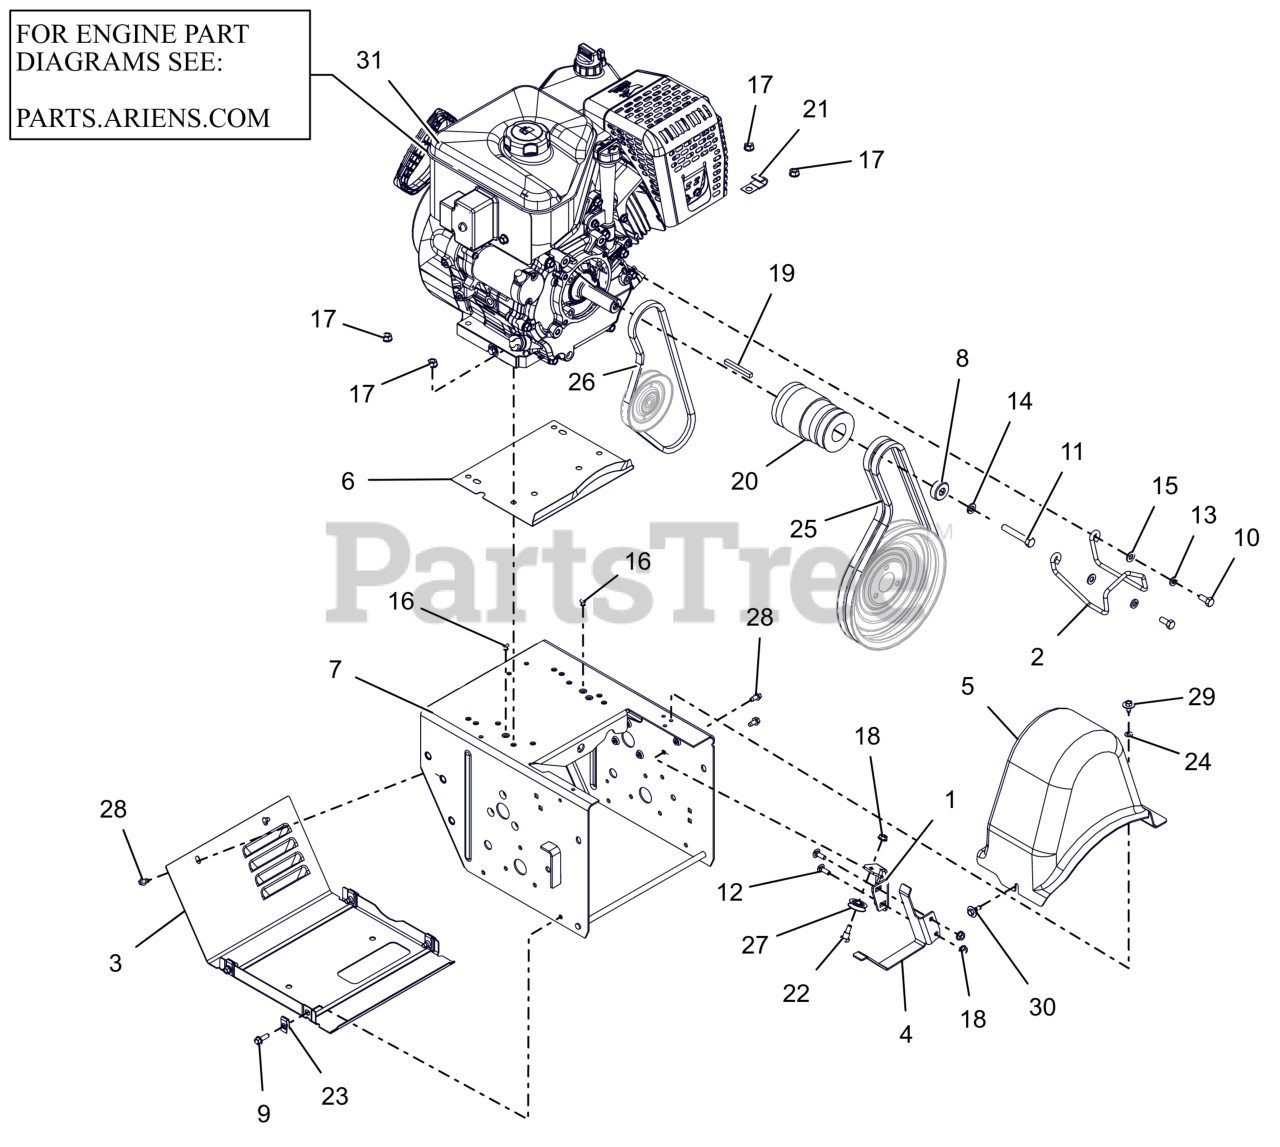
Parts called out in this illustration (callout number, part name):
1	BRACKET, CLUTCH CABLE
2	FINGER, BELT
3	COVER, BOTTOM - VENTILATED
4	FINGER, BELT - FLAT
5	COVER, BELT-LARGE
6	BAFFLE, WATER - LARGE BLOCK
7	FRAME, MAIN - PRO (WELDMENT)
8	BSHG, SPCR .406 X 1.250 X .500
9	BLT, HWH .25-20X.75 G5 ZCC
10	BLT, HEX .31-24X.750 G5 ZCC
11	BLT, HEX .38-24X2.25 G5 ZCC
12	BLT, RHSN .25-20X.750 G5 ZCC
13	WSHR, LK-HVY .312X.097 ZCC
14	WSHR,LK-REG .375X.094 ZCC
15	WSHR,FLT .344X.688X.065 ZCC
16	RVT, POP .1875 ZCC
17	NUT,LK-CTR-FLG .31-18 GF ZCC
18	NUT-LK-TOP-FLG .250-20 GF ZCC
19	KEY .25X.25X2.25
20	SHEAVE, COMBO HYDRO TRACK 4L
21	J-CLAMP
22	BOLT, SHLDR -.375 X .375 X .25-20
23	NUT-RTNR .25-20X.56
24	NUT-PUSH .25X.50 O.D.
25	V-BELT, HA-RAW EDGE (SET)
26	V-BELT, 4L-WRAPPED
27	PULLEY, CABLE
28	SCR-TAP .25-20X.50 HWH ZCC
29	SCR, TAP .25-20X.50 LG HWH ZCC
30	SCR-TAP .25-20X.5 CAPTIVE
31	ENGINE, AX420 GEN 3 120V/60W
